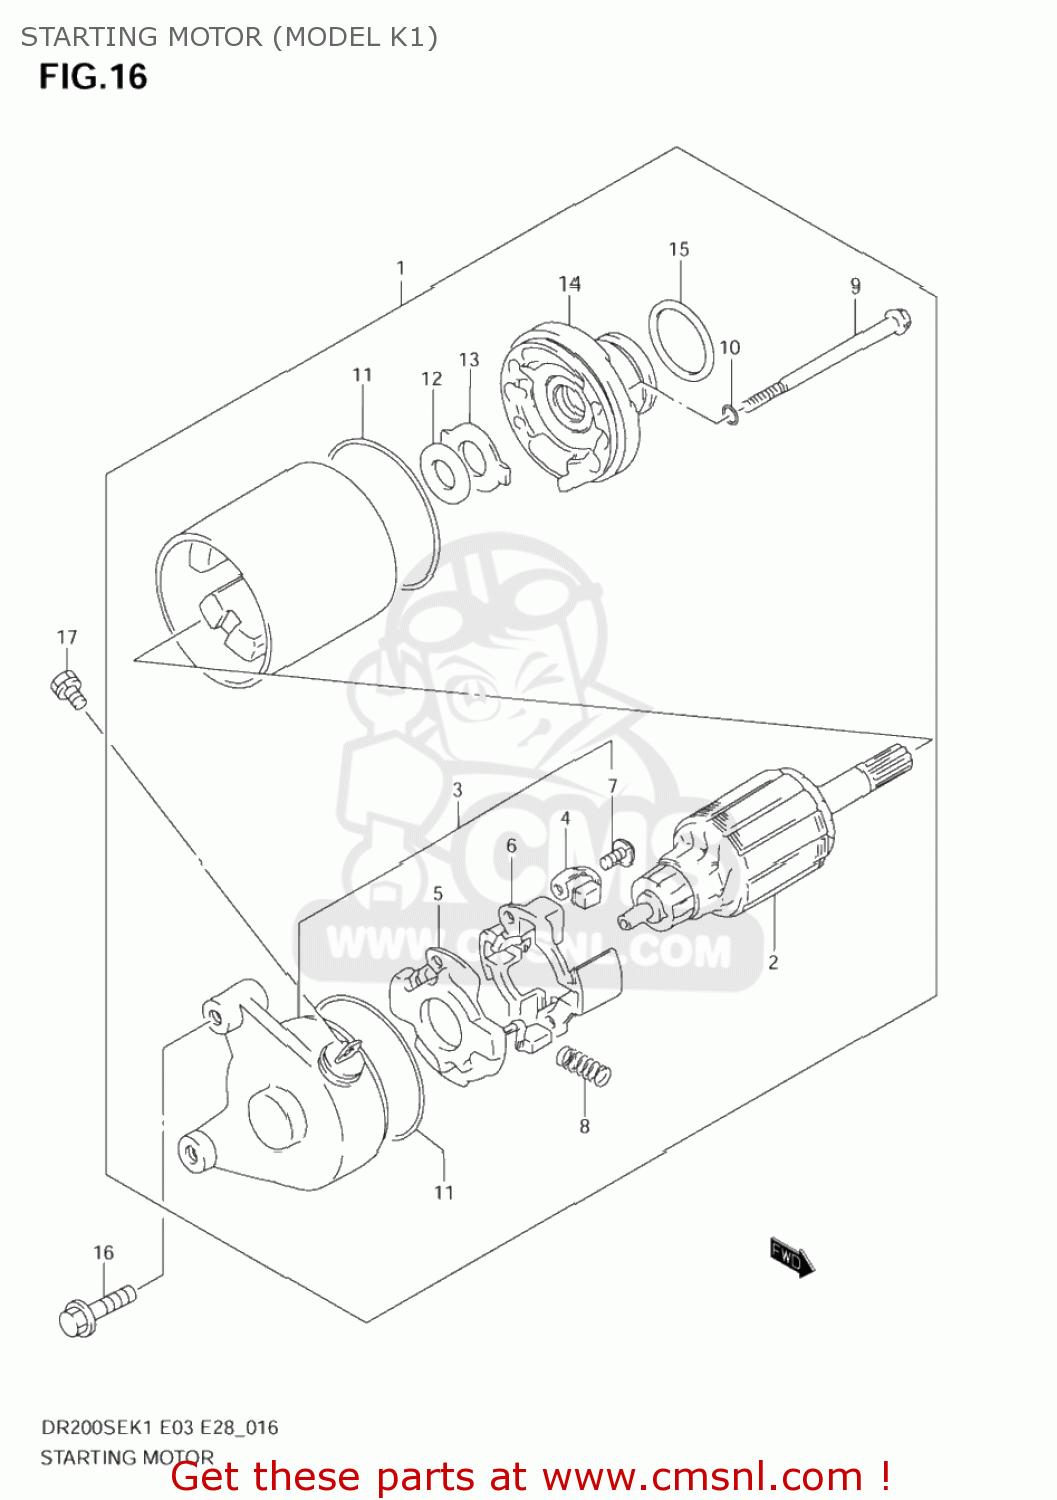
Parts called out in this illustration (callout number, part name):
1	MOTOR ASSEMBLY,STARTING
2	ARMATURE
3	FRAME ASSY,COMMUTATOR END
4	BRUSH
5	BRUSH SUB ASSY,STARTER
6	HOLDER,BRUSH
7	SCREW
8	SPRING
9	BOLT
10	O RING
11	O RING
12	SHIM
13	PLATE,LOCK
14	BRACKET
15	O RING(D:3,ID:24.5)
16	BOLT,G/S SWITC
17	SCREW(5X8)
